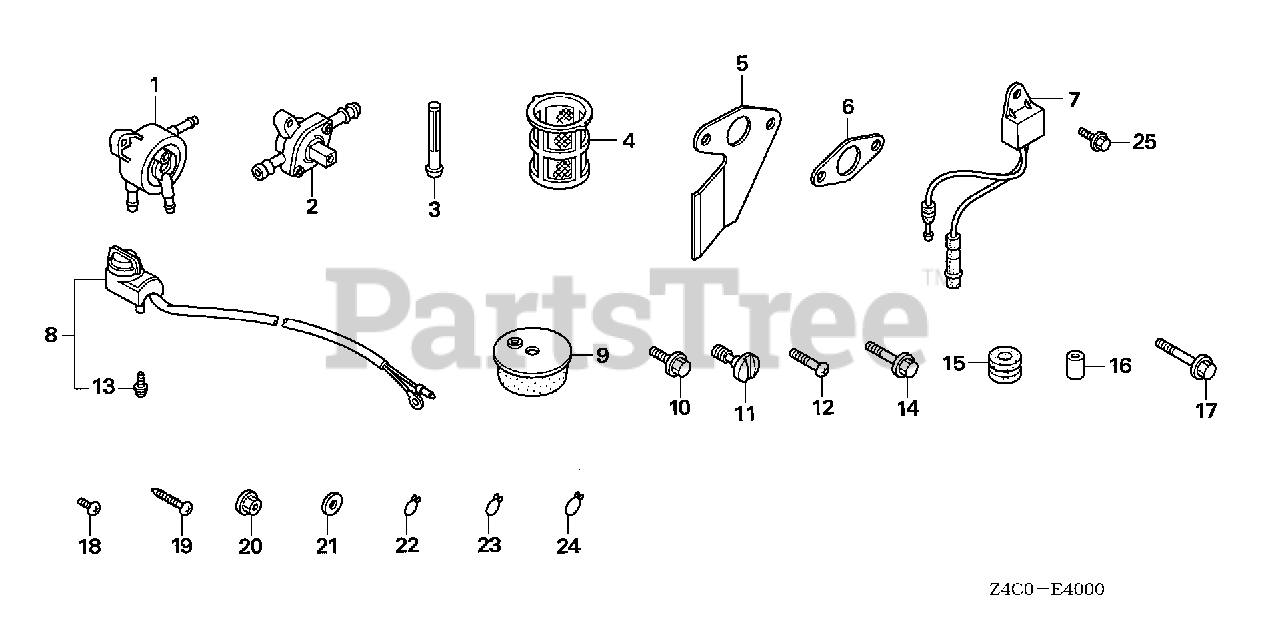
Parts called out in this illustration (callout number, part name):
1	PUMP ASSY., FUEL (MSDS)
7	ALERT UNIT, OIL
25	BOLT, FLANGE (6X8)
